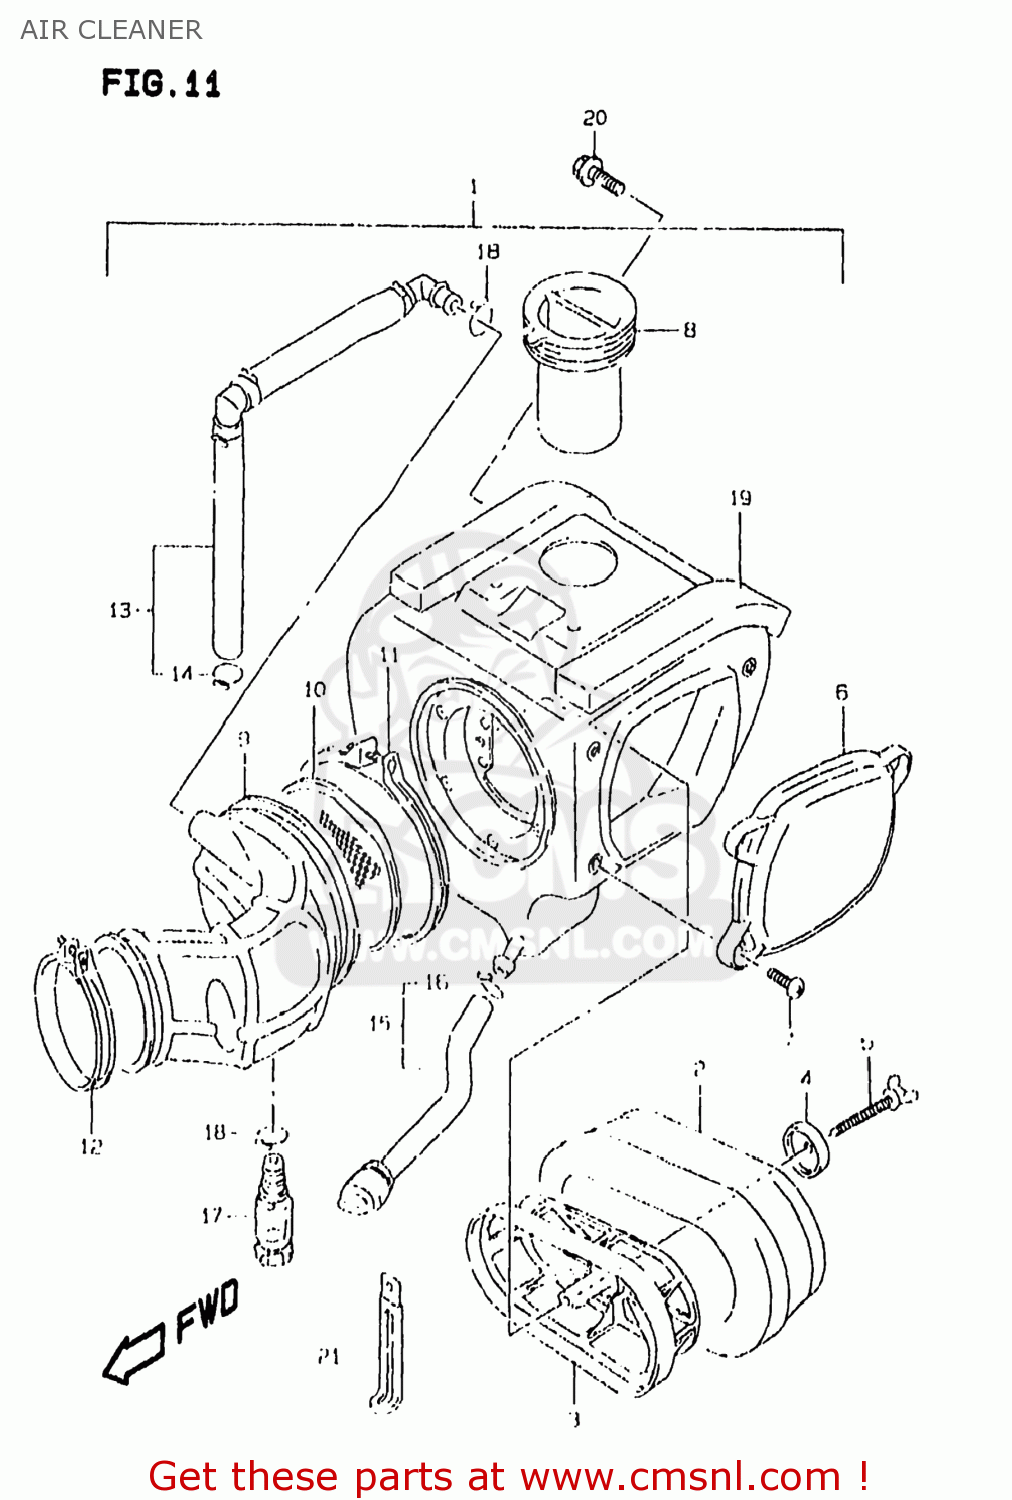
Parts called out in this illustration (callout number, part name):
1	CLEANER ASSY,AIR
2	FILTER
3	HOLDER,FILTER
4	WASHER,AIR CLEANER
5	BOLT,WING
6	CAP,AIR CLEANER
7	SCREW
8	TUBE,INLET
9	TUBE,OUTLET
10	TRAP,FRAME
11	CLAMP,OUTLET TUBE
12	CLAMP
13	TUBE,BREATHER
14	CLIP
15	TUBE,DRAIN A
16	CLIP
17	TUBE,DRAIN
18	CLIP
19	CUSHION
20	BOLT
21	CLAMP(L:80)
